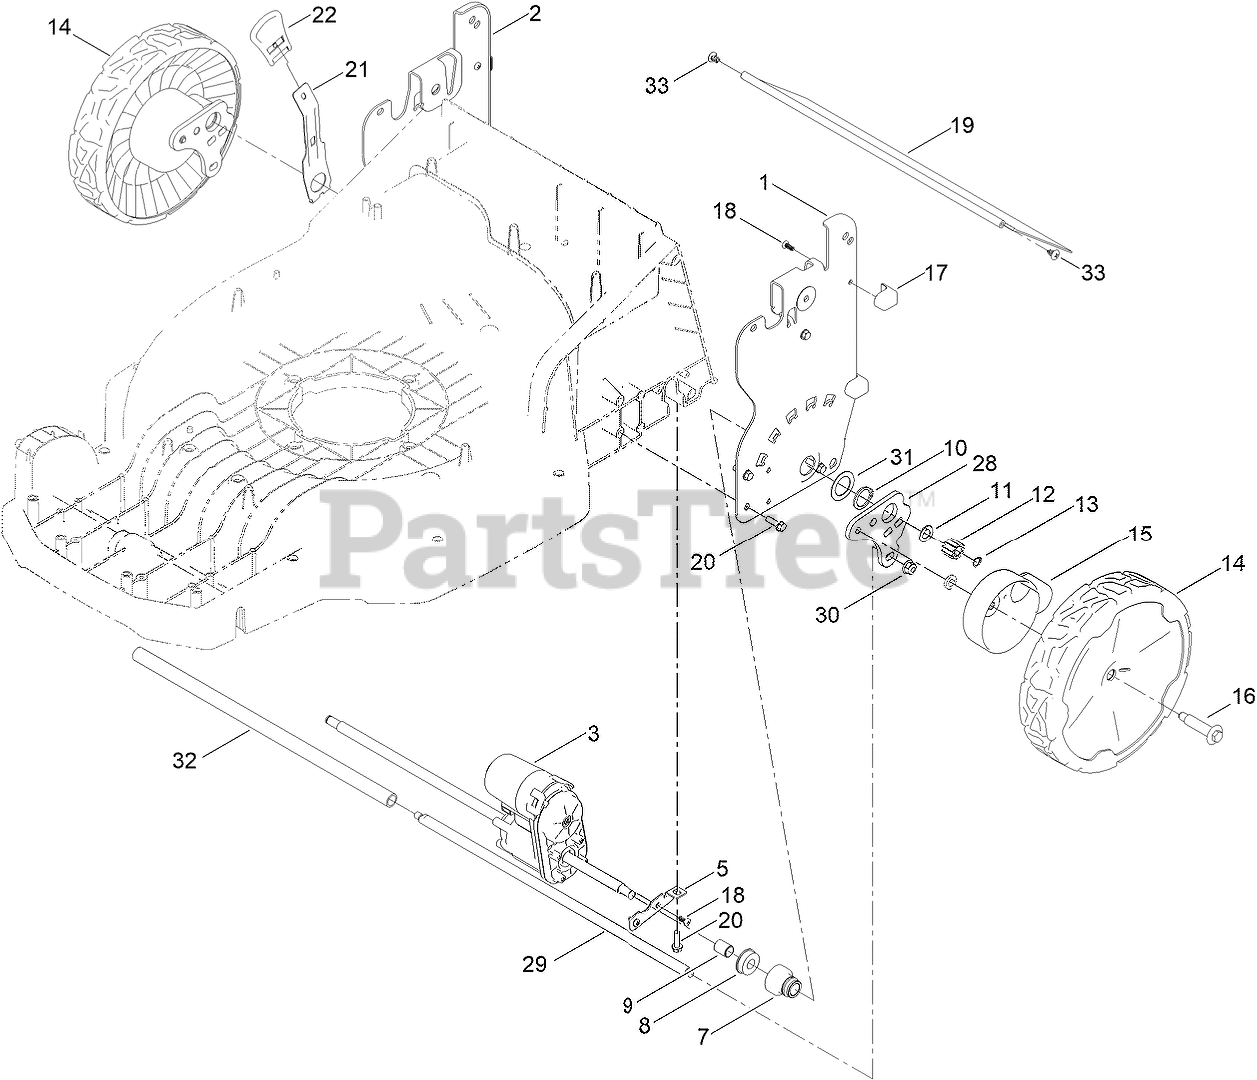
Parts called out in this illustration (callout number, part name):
1	PLATE-HOC, LH
2	PLATE-HOC, RH
3	TRANSMISSION-ELECTRIC, ME312
5	BRKT-TRANSMISSION
7	RETAINER-BEARING, HOC
8	BEARING-BALL
9	BUSHING-SLEEVE
10	RING-RETAINING
11	WASHER-THRUST
12	GEAR-PINION, 11T
13	RING-RETAINING, EXTERNAL
14	ASM-9.65" WHEEL, GEARED
15	ASM-COVER, GEAR
16	WHEEL BOLT
17	PAD-SMART STOW
18	SCREW-PLASTITE
19	SHIELD-TRAILING
20	SCREW-HWH
21	ARM-SPRING
22	KNOB-HOC
28	BRKT-PIVOT, REAR
29	ROD-CONNECTING, REAR
30	NUT-HF, NI
31	WASHER-FLAT
32	ROLLER-STRIPER
33	SCREW-THD
